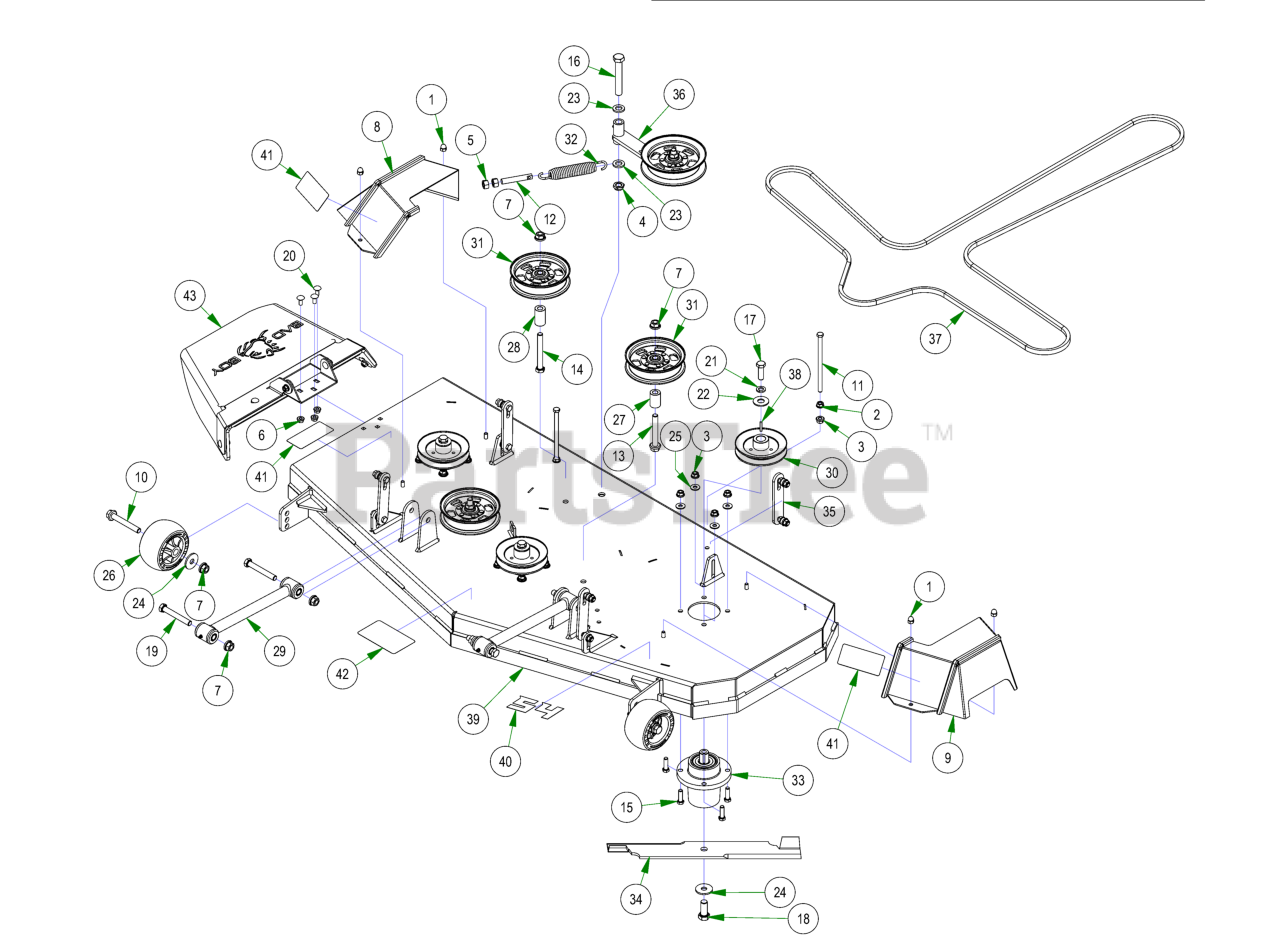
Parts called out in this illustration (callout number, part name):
1	5/16-18 ACORN NUT HIGH-CROWN ZC
2	3/8-16 HEX SERRATED FLANGE NUT HARD/ZINC
3	3/8-16 NYLON INSERT FLANGE LOCKNUT (GR.F) ZINC
4	5/8-11 NYLON INSERT JAM LOCKNUT ZINC
5	1/2-13 HEX NUT ZINC
6	5/16-18 NYLON INSERT FLANGE LOCKNUT ZINC
7	1/2-13 NYLON INSERT FLANGE LOCKNUT ZINC
8	2021 Maverick 54”/60” RH Pulley Cover
9	2021 Maverick 54”/60” LH Pulley Cover
10	1/2-13 X 90MM HEX FLANGE BOLT W/SHOULDER (GR.8) ZINC
11	3/8-16 X 6.5 HEX CAP SCREW (GR.5) ZINC
12	All Thread
13	1/2-13 X 3-1/2 HEX FLANGE BOLT (GR.8) ZINC
14	1/2-13 X 4 HEX CAP SCREW (GR.8) ZINC YELLOW
15	3/8-16 X 1-1/4 HEX CAP SCREW (GR.5) ZINC
16	5/8-11 X 4 HEX CAP SCREW (GR.8) ZINC YELLOW
17	1/2-20 X 1-1/2 HEX CAP SCREW (GR.5) ZINC
18	5/8-18 X 1-1/2 HEX CAP SCREW (GR.8) ZINC YELLOW
19	1/2-13 X 3-1/2 HEX CAP SCREW (GR.5) ZINC
20	5/16-18 x 3/4 Carriage Bolt
21	1/2 SPLIT LOCKWASHER (GR.8) ZINC/YELLOW
22	5/8 USS FLAT WASHER (1-3/4" OD) GR.8 ZINC YELLOW
23	.635 ID X 1.120 OD X .140 THICK FLAT WASHER NYLON
24	1/2 BELLEVILLE WASHER (1-5/8 OD X .140 THK) ZINC
25	5/16 USS FLAT WASHER (7/8 OD) ZINC
26	Deck Wheel
27	.502 ID X .750 OD X 1.500 Long Spacer
28	1 3/4" Pulley Spacer
29	Hybrid Turnbuckle/Deck Locator
30	54 MZ Spindle Pulley
31	5-3/4 Idler Pulley
32	Deck Idler Spring
33	Spindle Assembly-MZ
34	54" Fusion Blade for Avenger/ZT/Mav/Outlaw/Revolt
35	Deck Hanger Assembly
36	2017 MZ/ZT Deck Idler Assembly
37	B155.75 Deck Belt
38	3/16 X 1 SQ MACHINERY KEY 1018 STL ZINC
39	2023 54" x 4" Deck
40	54" Deck Decal
41	Danger Decal-Spindle/Discharge
42	Deck Belt Route Decal
43	MZ Discharge Chute Assembly
